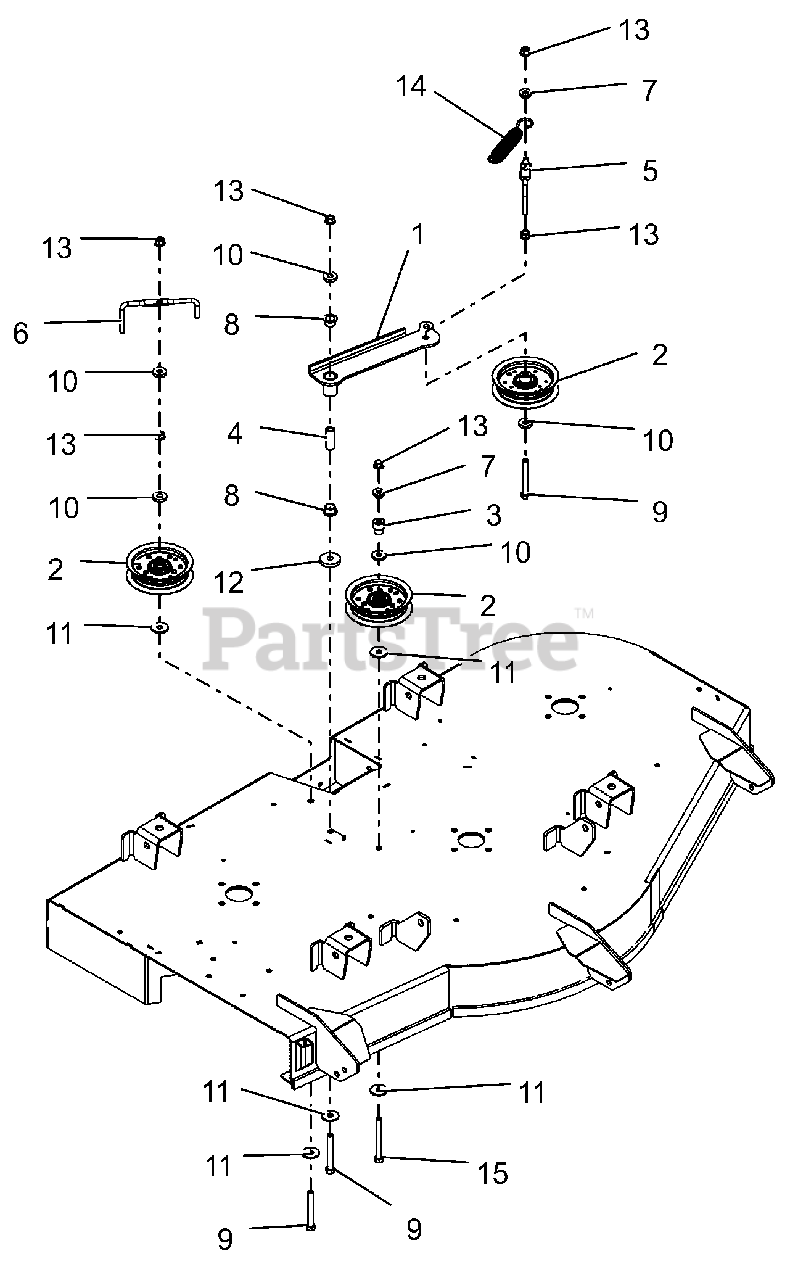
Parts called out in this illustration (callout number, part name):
1	WLDMT, IDLER ARM-52"
2	ASM, IDLER 4"
3	BUSHING, IDLER (P/M)
4	SPACER, .375IDX.625ODX1.66 PM
5	WIREFORM, BELT FINGER
6	WIREFORM, BELT FINGER
7	BSHG-FLG .385X.500X.875X.406
8	BSHG-FLG, .625X.750X.500X1.00
9	BLT, HEX .38-16X3.00F G5 ZCC
10	WSHR, FLT .406X1.00X.188 ZCC
11	WSHR FL STL .406X1.25X.10ZC120
12	WSHR, FLT .406X1.50X.245 ZCC
13	NUT-LK-TOP-FLG .38-16 ZC120
14	SG-TENS .135X.98X6.0 WLD 62
15	BLT, HEX .38-16X3.50 G5 ZCC
